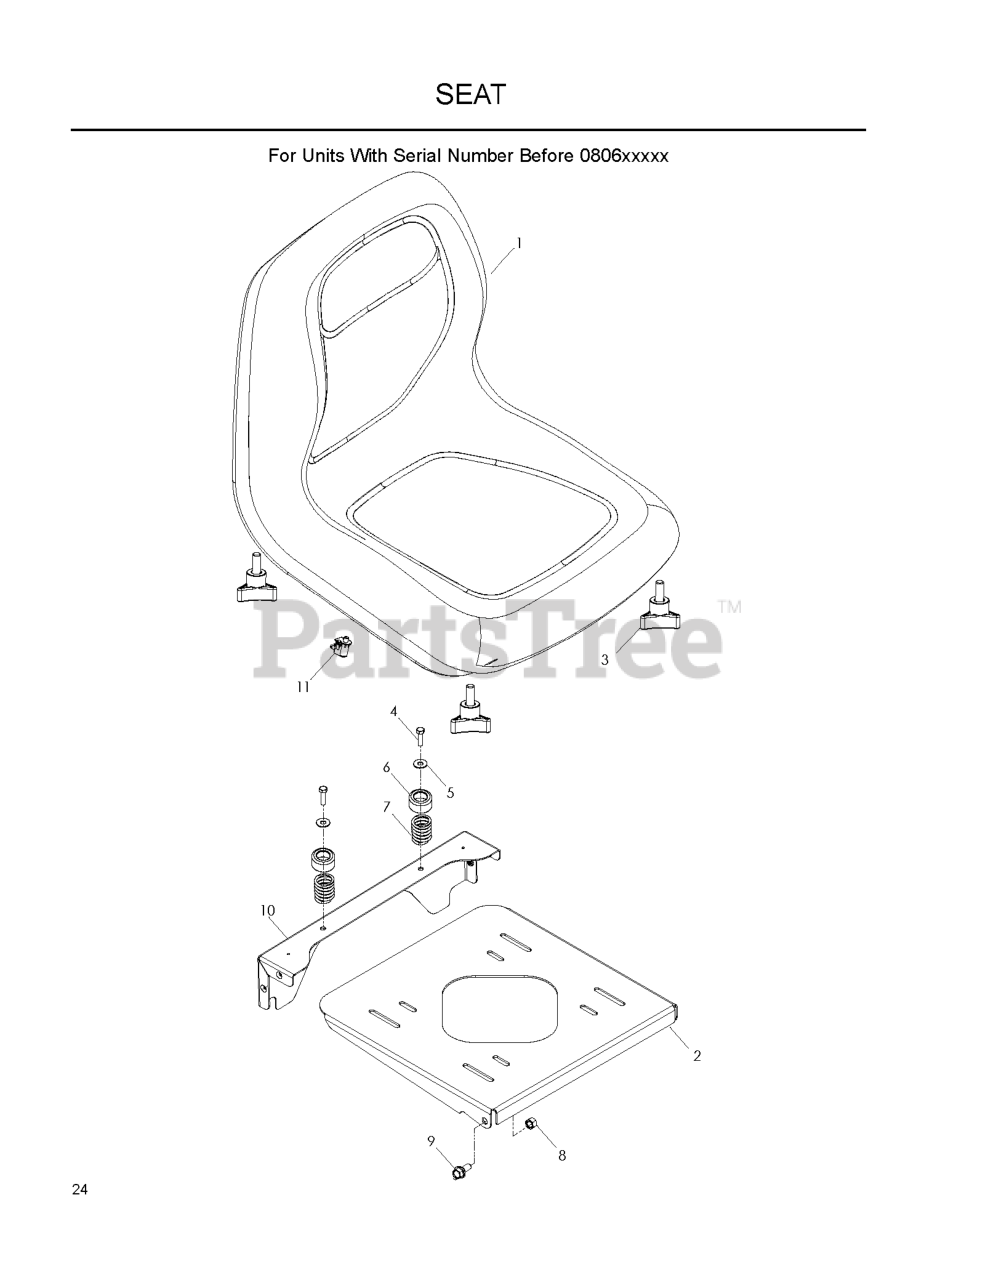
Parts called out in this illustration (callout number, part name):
1	SEAT.XH150.LOWBACK.GREY.ZTR
2	SEAT MOUNT, BLACK
3	KNOB W/STUD
4	BOLT, SHOULDER
5	WASHER 3/8 FLAT
6	CAP, SPRING COVER
7	SPRING, SEAT
8	NUT 5/16 NYLOC
9	HCS 3/8C X 1 1/4 GR5
10	REAR SEAT SUPPORT ORANGE
11	SEAT SWITCH
